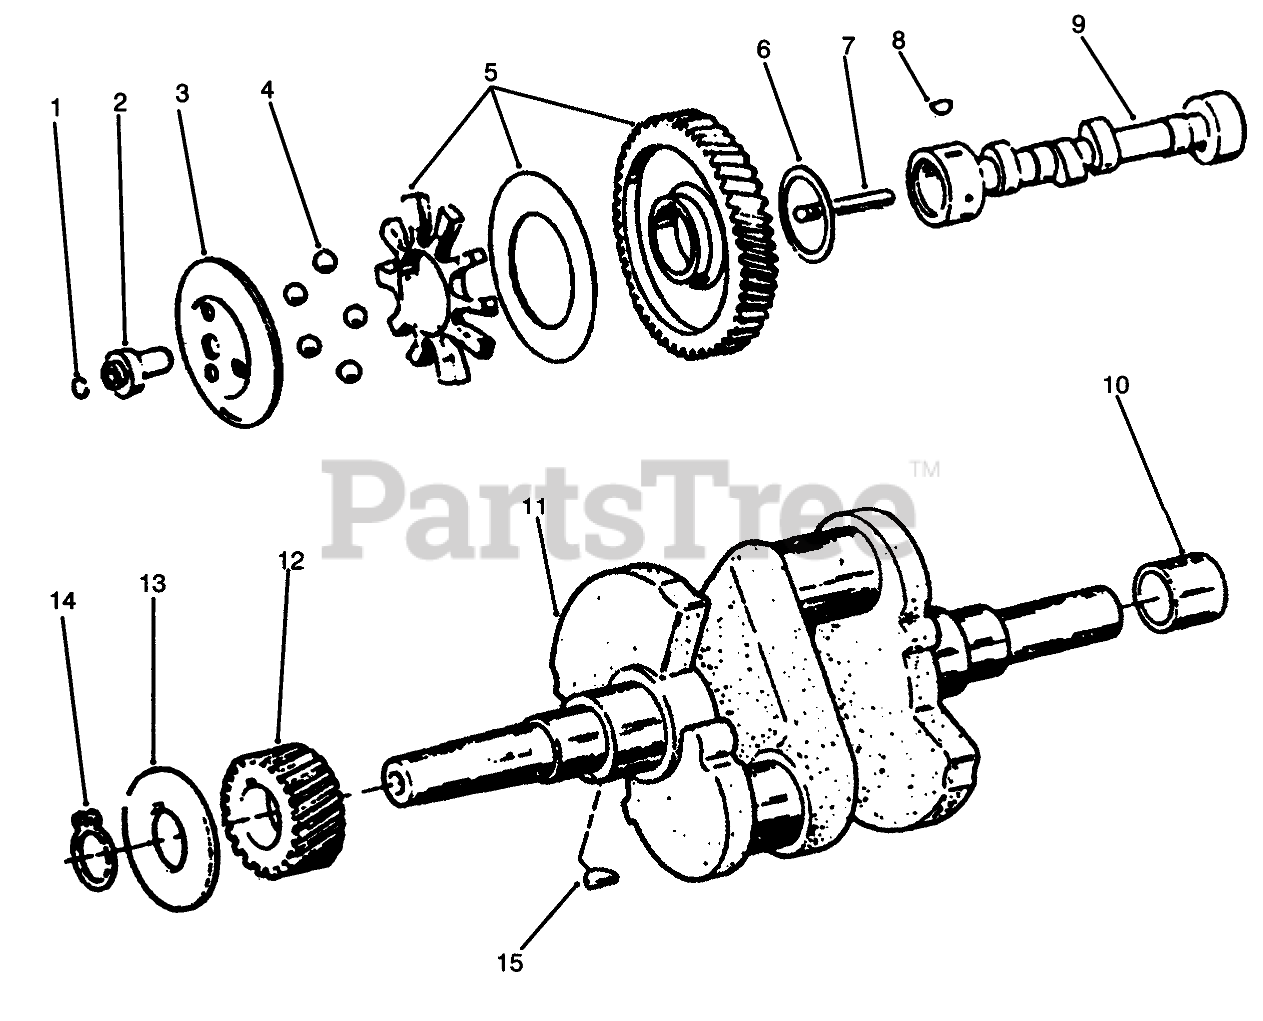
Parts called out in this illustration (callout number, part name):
2	HUB-GOVERNOR CUP
3	CUP-GOVERNOR
4	BEARING
5	Gear-Camshaft (Incl. Gear, Spacer, & Plate)
6	WASHER-THRUST
7	PIN-CENTER
9	Camshaft (Incl. Ref. #7)
10	BEARING SLEEVE
11	Crankshaft (Incl. Ref. #15)
13	WASHER
